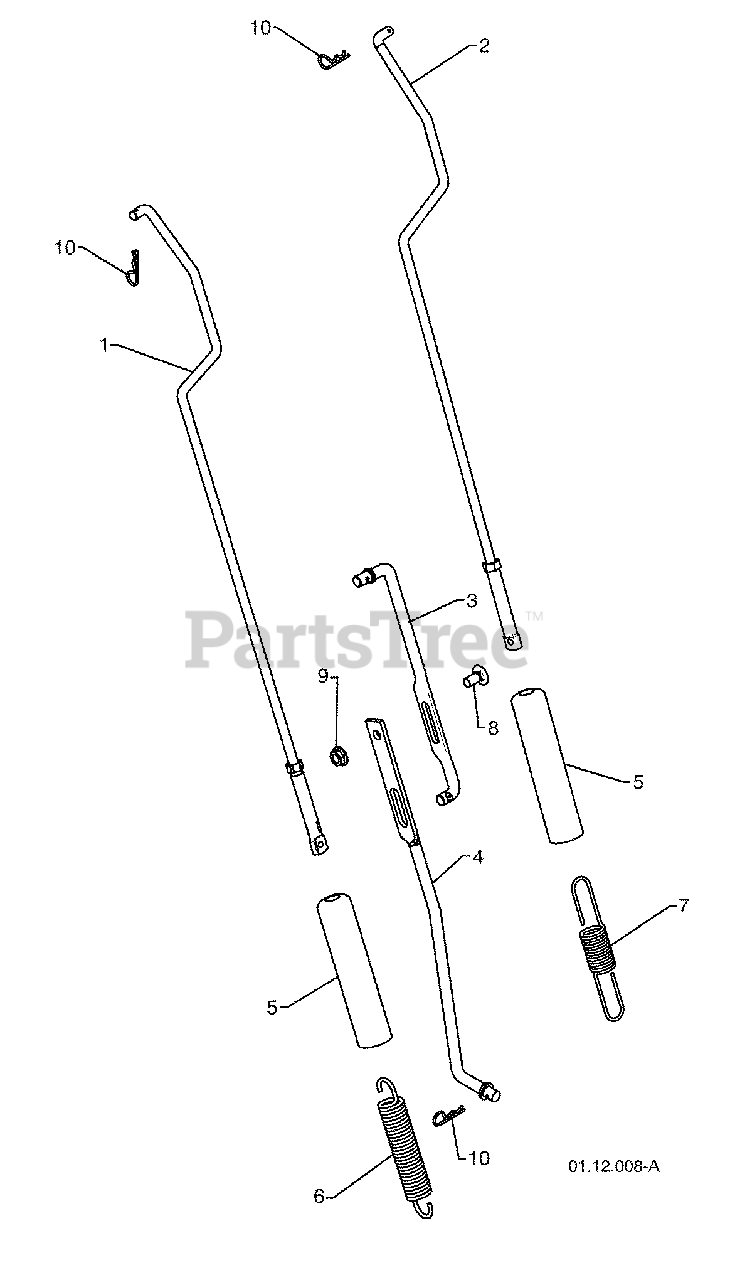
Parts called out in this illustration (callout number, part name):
1	IMPELLER ROD ASSEMBLY
2	TRACTION ROD ASSEMBLY
3	SHIFTER ROD TOP
4	SHIFTER ROD BOTTOM
5	SPRING SLEEVE
6	IMPELLER SPRING
7	TRACTION SPRING
8	CARRIAGE BOLT 5/16-18 X .750
9	NUT 5/16-18
